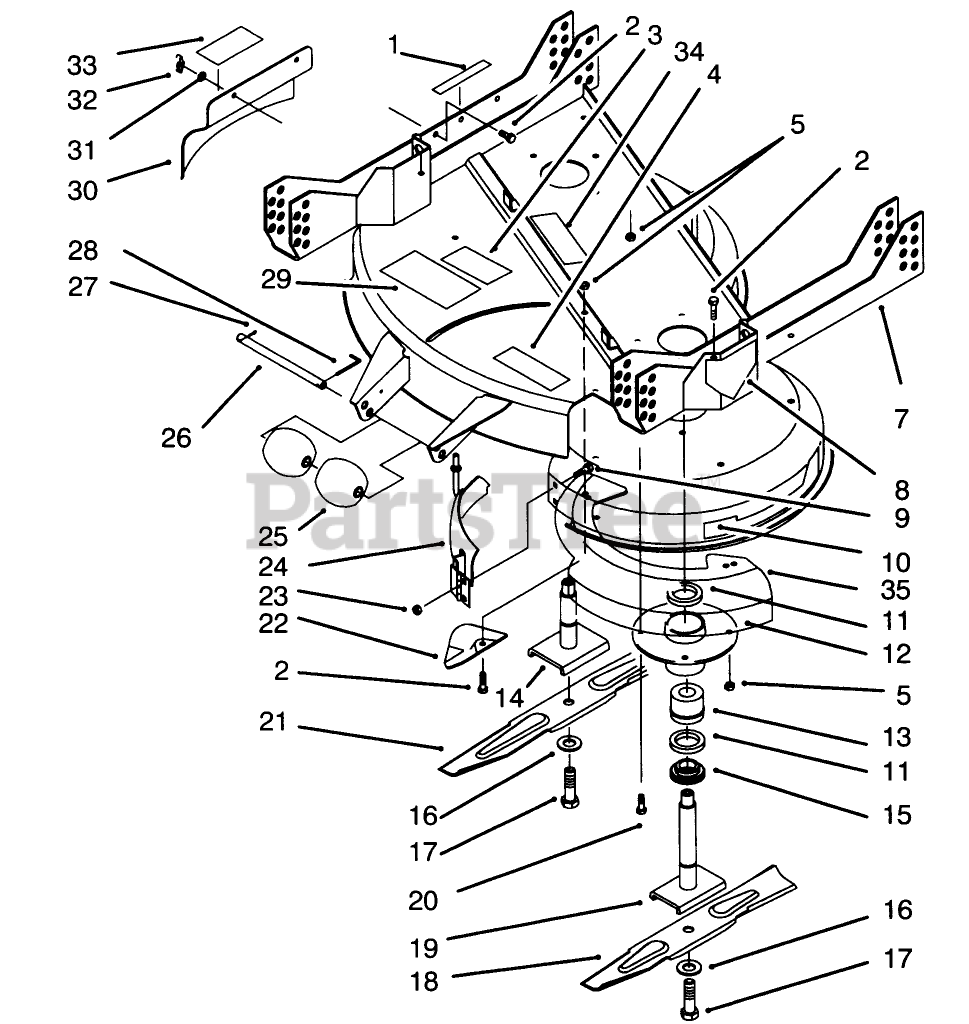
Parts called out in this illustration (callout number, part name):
1	DECAL-DANGER, DEFLECTOR
2	SCREW-HH
3	DECAL-TORQUE
4	DECAL - DISCHARGE DOOR
5	NUT-LOCK, NI
7	Deck Support (Incl. Ref. #3, 4, 6, 8, & 29)
8	DECAL-DANGER
9	SCREW-CARRIAGE
10	DECAL - 37"
11	SEAL-OIL
12	SPINDLE HOUSING
13	BEARING ASM
14	SHAFT-SPINDLE
15	SPACER
16	WASHER-LOCK
17	SCREW-BLADE
18	Blade
19	SHAFT-SPINDLE
20	SCREW-HH
21	Blade
22	PLATE-KICKER
23	NUT-KEPS
24	Cover-Front
25	ROLLER
26	SHAFT-ROLLER
27	PIN-COTTER
28	PIN-SPECIAL
29	DECAL-DANGER, THROWN OBJECT
30	Cover-Discharge
31	WASHER-LOCK
32	NUT-WING
33	DECAL - DANGER
34	DECAL-DANGER
35	Insert-Deck
